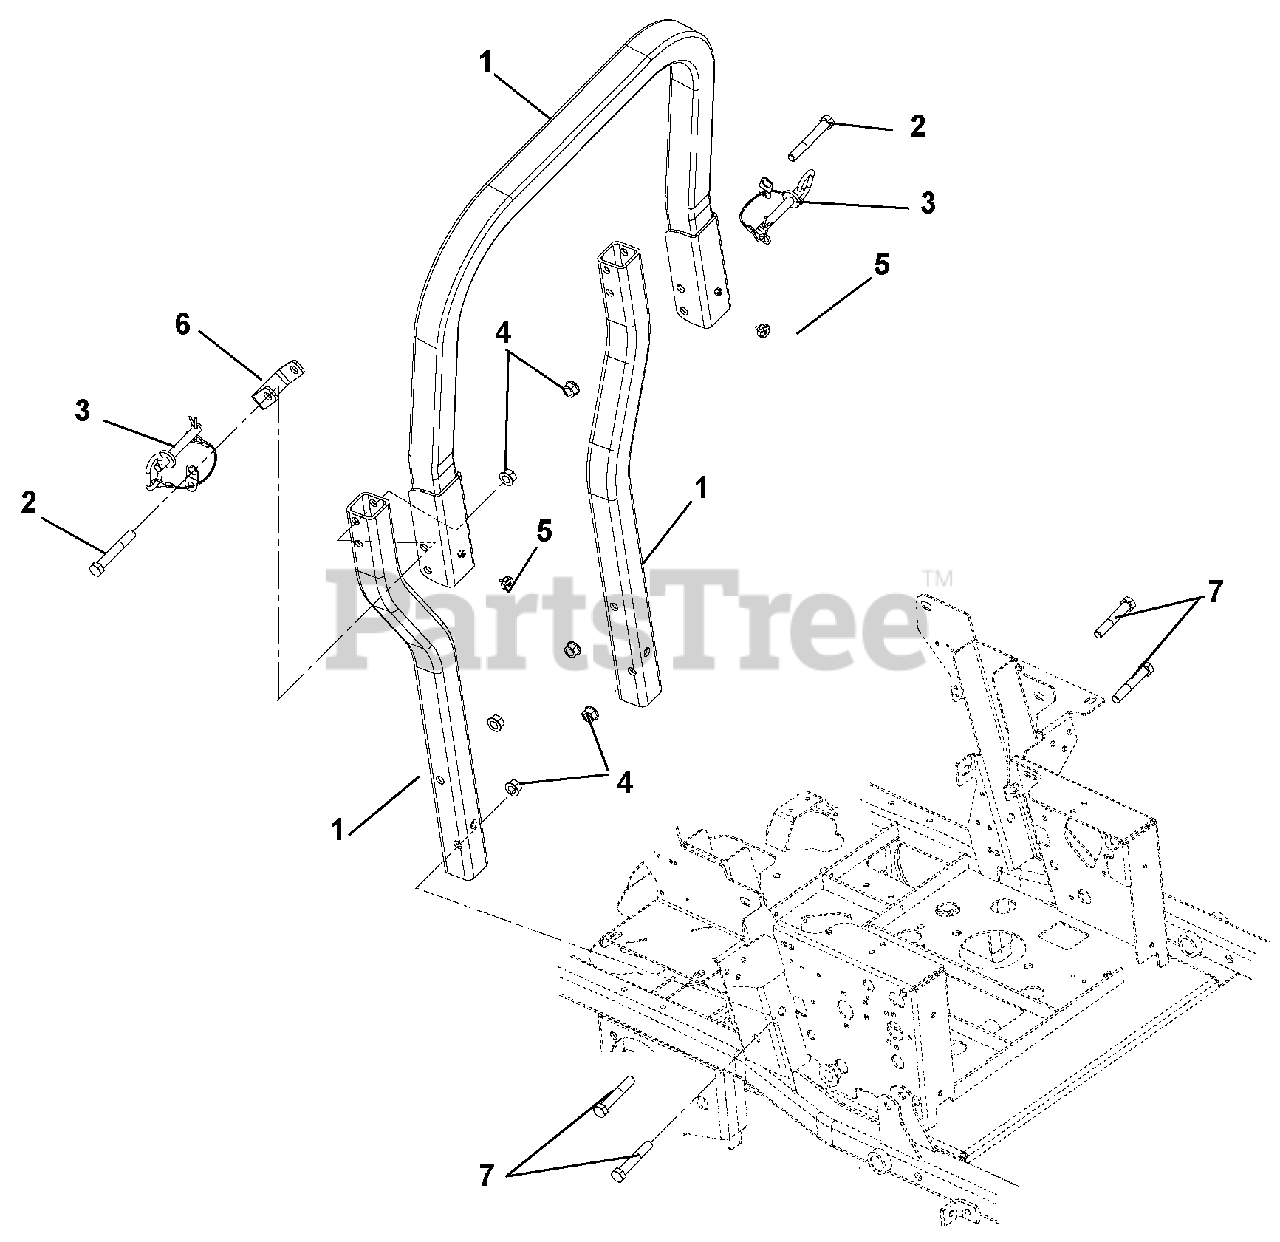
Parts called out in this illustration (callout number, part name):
1	ROPS, PM200 Replacement Kit
2	Bolt, Hex .50-13 x 3.50 Grade 5
3	Assembly, ROPS PIN/LANYARD
4	Nut, Locking Top Flange .50-13
5	Knob, Round .312-18 x .750
5	Clip, ROPS Anti-Rattle
6	Bracket, ROPS Stop, Pro-Master
7	Bolt, Hex .50-13 x 3.00 Grade 5
